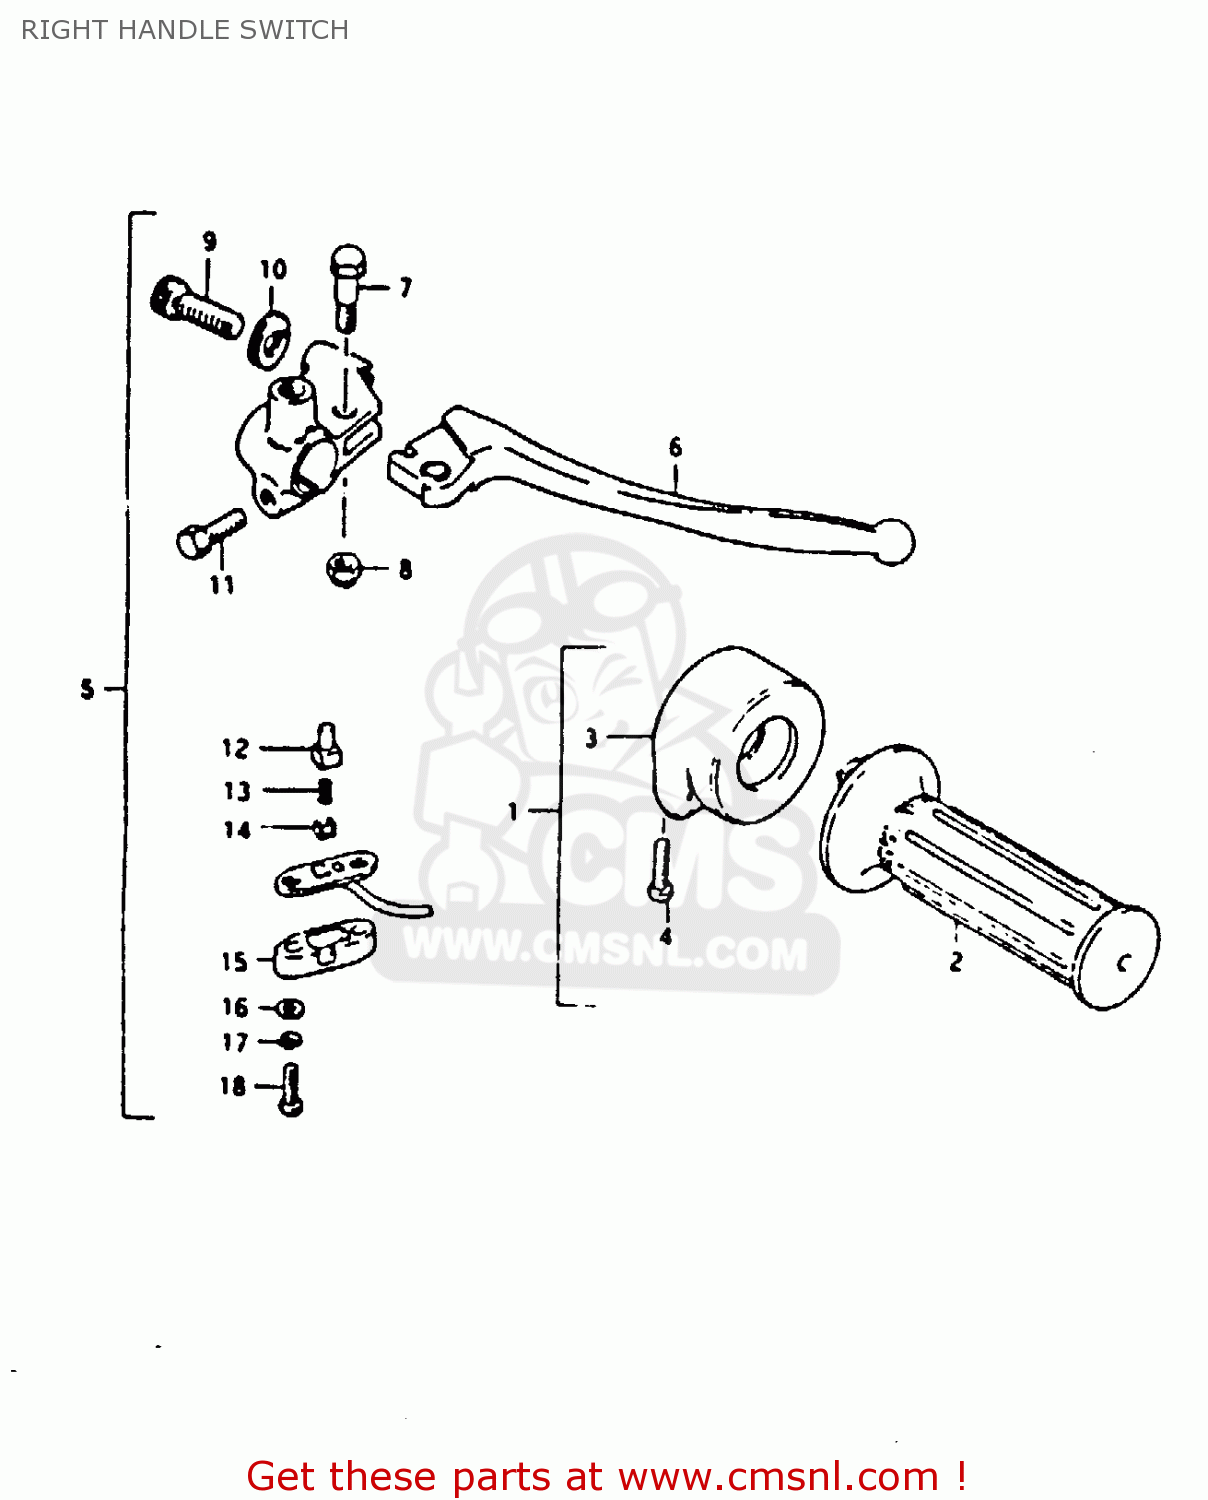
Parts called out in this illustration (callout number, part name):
1	GRIP ASSY, THROTTLE
2	GRIP,THROTTLE
3	CASE ASSY,THROTTLE
4	SCREW
5	LEVER ASSEMBLY,BRAKE
6	LEVER,BRAKE
7	BOLT,LEVER
8	NUT 6MM
9	ADJUSTER,CABLE
10	NUT,CABLE ADJUSTER
11	BOLT
12	HOLDER
13	SPRING
14	PLATE
15	COVER,FR BK TERMINAL BASE
16	WASHER
17	LOCK WASHER
18	SCREW
